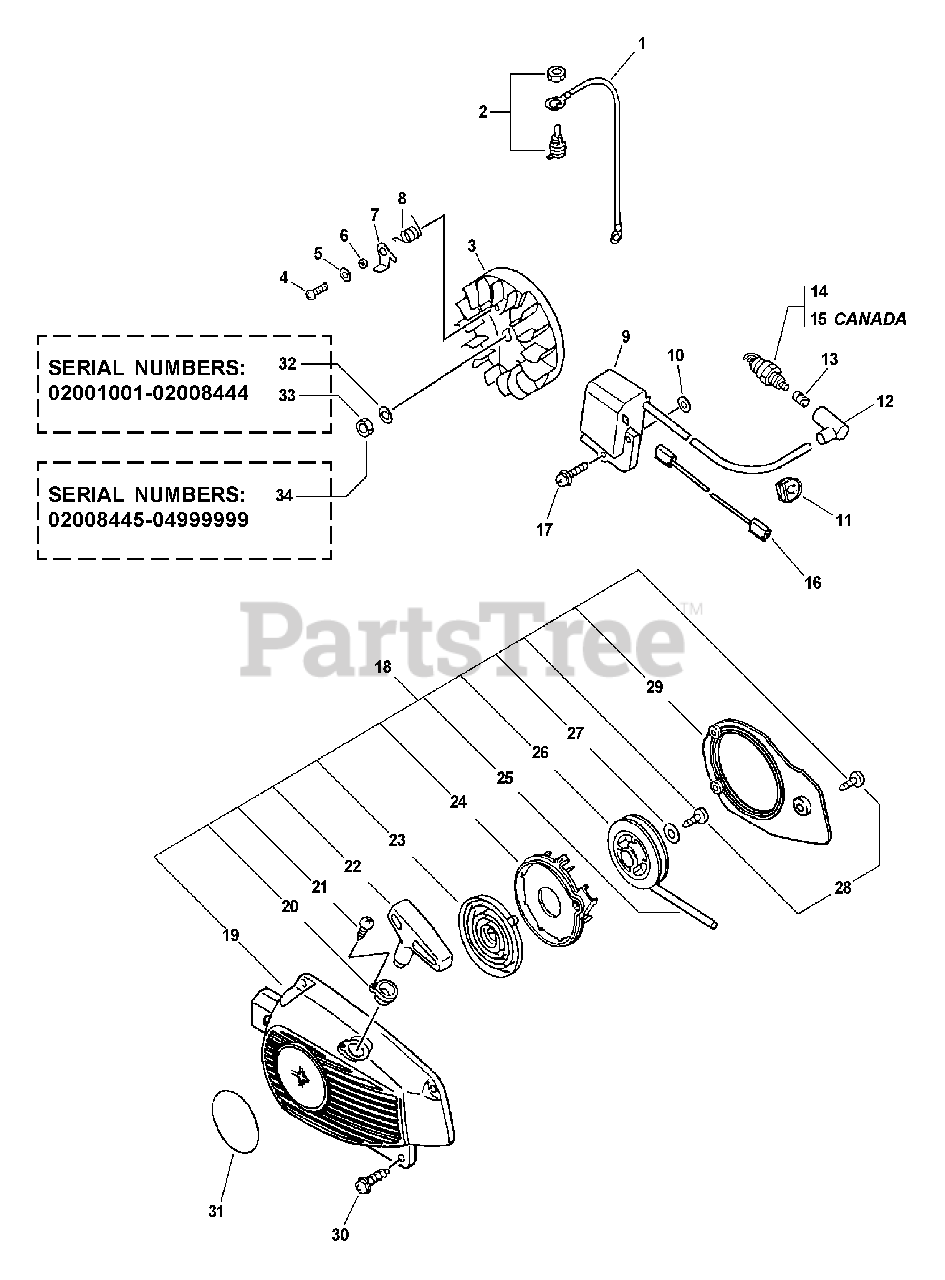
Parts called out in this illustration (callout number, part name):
1	LEAD - GROUND
2	IGNITION SWITCH KIT
3	FLYWHEEL
4	SCREW - 5X12
5	WASHER - 5
7	PAWL, STARTER
8	SPRING, RETURN
9	COIL, IGNITION
12	CAP, SPARK PLUG
13	TERMINAL, SPARK PLUG CAP
14	SPARK PLUG -- BPM-8Y
15	SPARK PLUG -- BPMR-8Y
16	LEAD - IGNITION
17	SCREW - 5X22
18	STARTER ASSY
19	CASE, STARTER - GRAY
20	GUIDE, ROPE
21	SCREW - 3X14
22	GRIP, STARTER
23	REWIND SPRING ASSY
24	PLATE, STARTER
25	ROPE, STARTER - 3X850
26	REEL, ROPE
28	SCREW - 4X14
30	SCREW - 4X16
31	LABEL - ECHO
32	NUT - 8
33	WASHER - 8
34	NUT - 8 -- FLANGE
